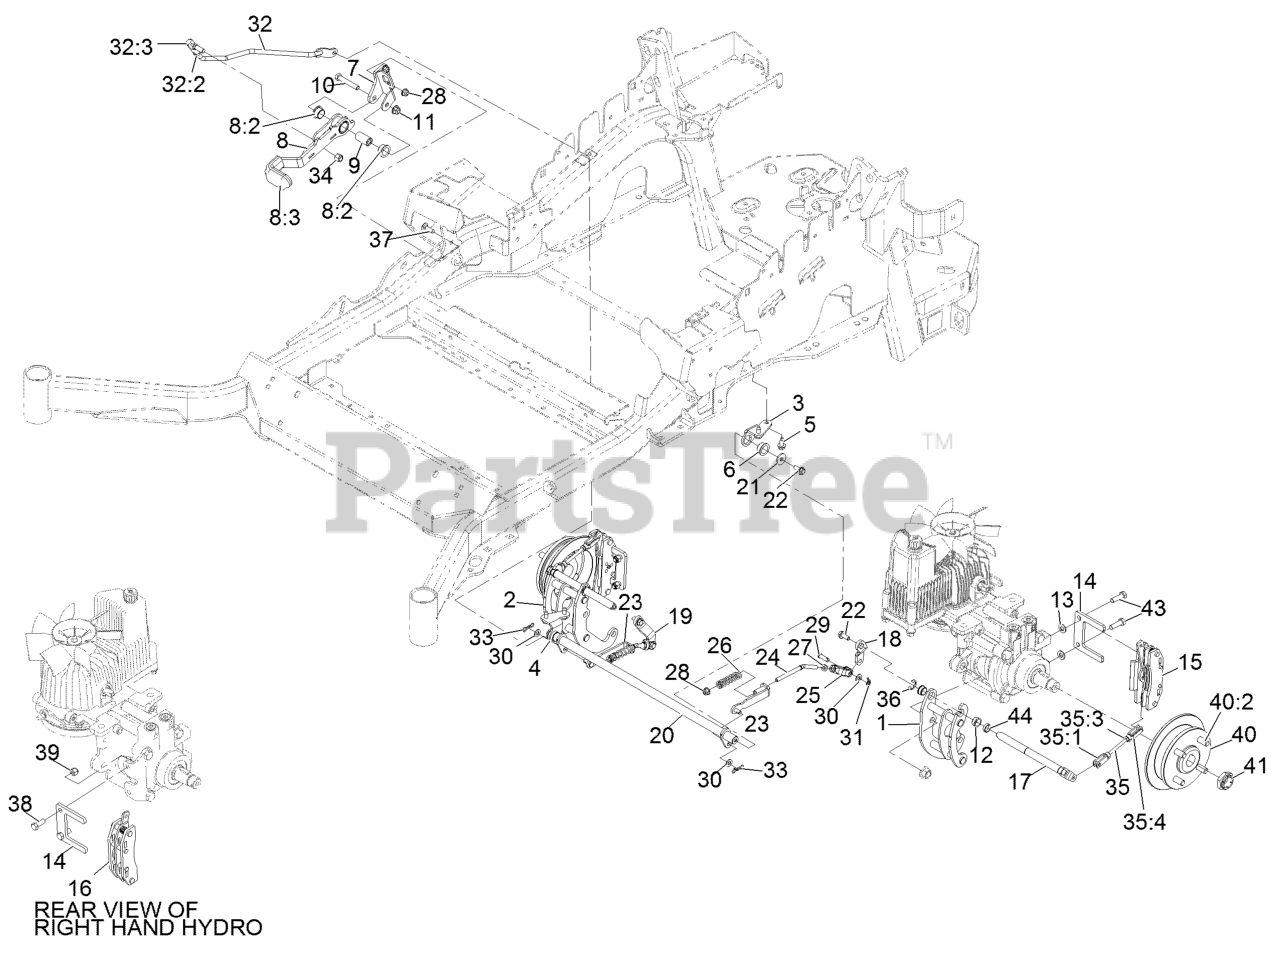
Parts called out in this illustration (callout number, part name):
1	MOUNT-BELLCRANK, LH
2	MOUNT-BELLCRANK, RH
3	MOUNT-PIVOT, LH
4	MOUNT-PIVOT, RH
5	Screw-HWH 5/16-18 X 3/4 Tf
6	BUSHING-FLANGE
7	BRACKET-MOUNT
8	BRAKE LEVER ASM
8:2	BUSHING-FLANGE
8:3	GRIP-LEVER
9	HANDLE-PIVOT, BRAKE
10	SCREW-HH
11	NUT-HF, NI
12	BUSHING
13	WASHER-FLAT
14	PLATE-MOUNT, BRAKE
15	CALIPER-BRAKE
16	CALIPER-BRAKE, RH
17	BELLCRANK
18	ARM-INNER, LH
19	ARM-INNER, RH
20	SHAFT-CROSS
21	WASHER-FLAT
22	SCREW-HHF
23	BRACKET-L
24	LINKAGE-MID
25	YOKE-OFFSET
26	SPRING-COMPRESSION
27	NUT-JAM
28	NUT-HF, NI
29	PIN-CLEVIS
30	WASHER-PLAIN
31	PIN-COTTER, LOCKING
32	FRONT LINKAGE ASM
32:2	END-TIE ROD, RH
32:3	NUT-HJ
33	PIN-COTTER, LOCKING
34	NUT-LOCK
35	REAR LINKAGE ASM
35:3	NUT-JAM
35:4	PIN-CLEVIS, SPRING
37	BOLT-CARR
38	SCREW-HH
39	NUT-LOCK, NI
40	WHEEL HUB ASM
40:2	STUD-WHEEL
41	LOCKNUT
43	SCREW-LOCK, PATCH
